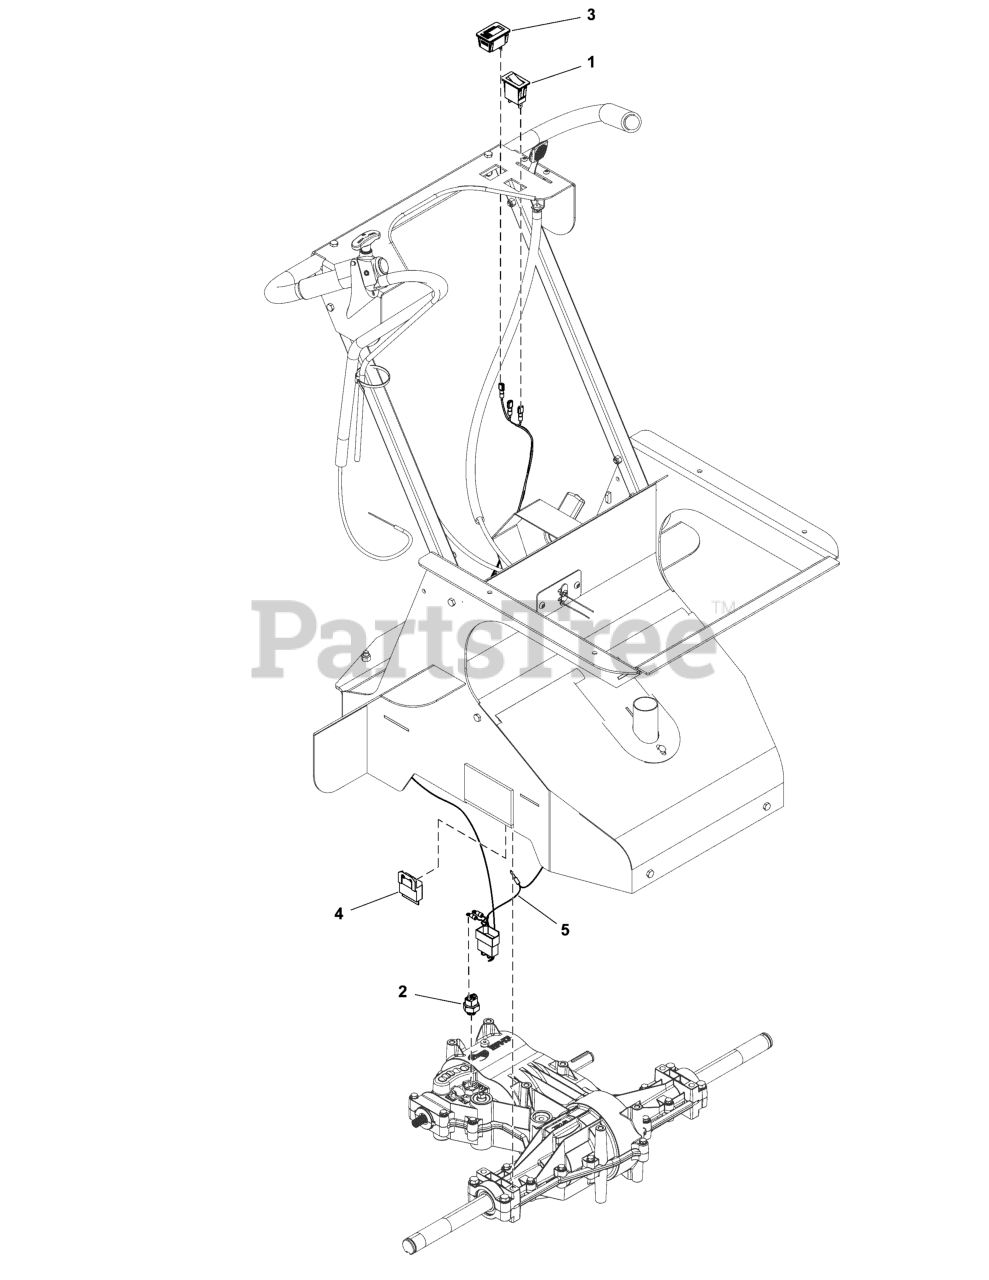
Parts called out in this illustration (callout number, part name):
1	SWITCH, ROCKER ON/OFF
2	PEERLESS NEUTRAL START SWITCH
3	METER, TACH/HOUR INDUCTIVE PICKUP
5	HARNESS, WIRING ROVER POSITIVE VOLTAGE
